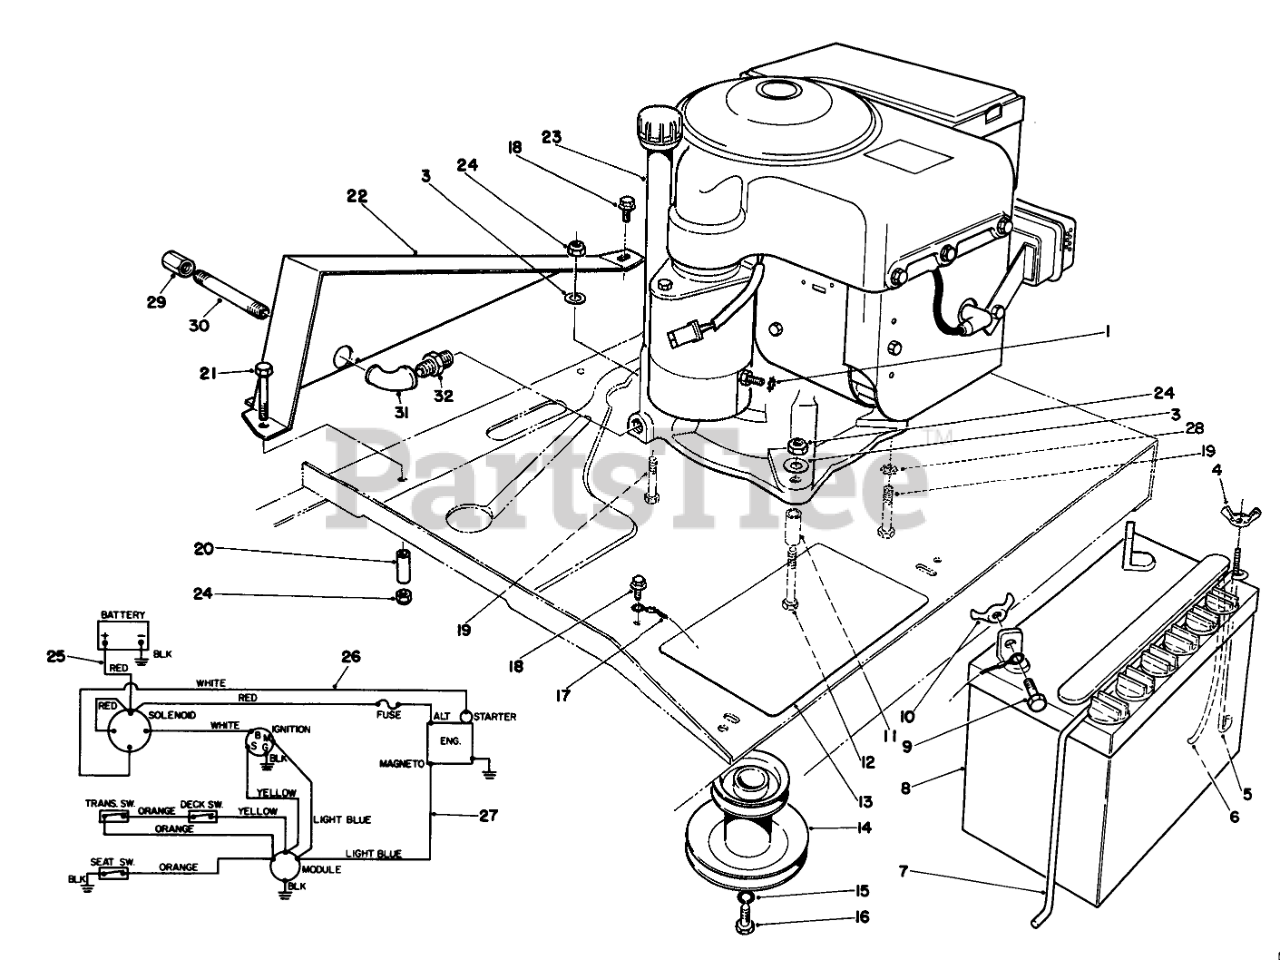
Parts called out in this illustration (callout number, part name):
1	WASHER-LOCK/EXT
3	WASHER-PLAIN
4	NUT-WING SPECL
5	POST-BATTERY
6	TUBE-BATT DRAIN/80-2600
7	HOLDDOWN-BATTERY
8	Battery
9	SCREW-HH
10	NUT-WING
11	SPACER-PIVOT
12	SCREW-HH
13	PAD-SKID, ANTI
14	Pulley-Engine
15	WASHER-FLAT
16	SCREW-HH
17	WIRE ASM(BATT/GRD.
18	SCREW-HWHTF
19	SCREW-HH
20	GUIDE-BELT
21	SCREW-HH
22	Guard-Chain
23	Engine-8 H.P. B & S
24	NUT-LOCK, NI
25	WIRE ASM - BATT TO SOL
26	WIRE ASSEMBLY
27	WIRING HARNESS
28	WASHER-LOCK
29	CAP-PIPE
30	NIPPLE-PIPE
31	ELBOW-STREET
32	BUSHING-PIPE
